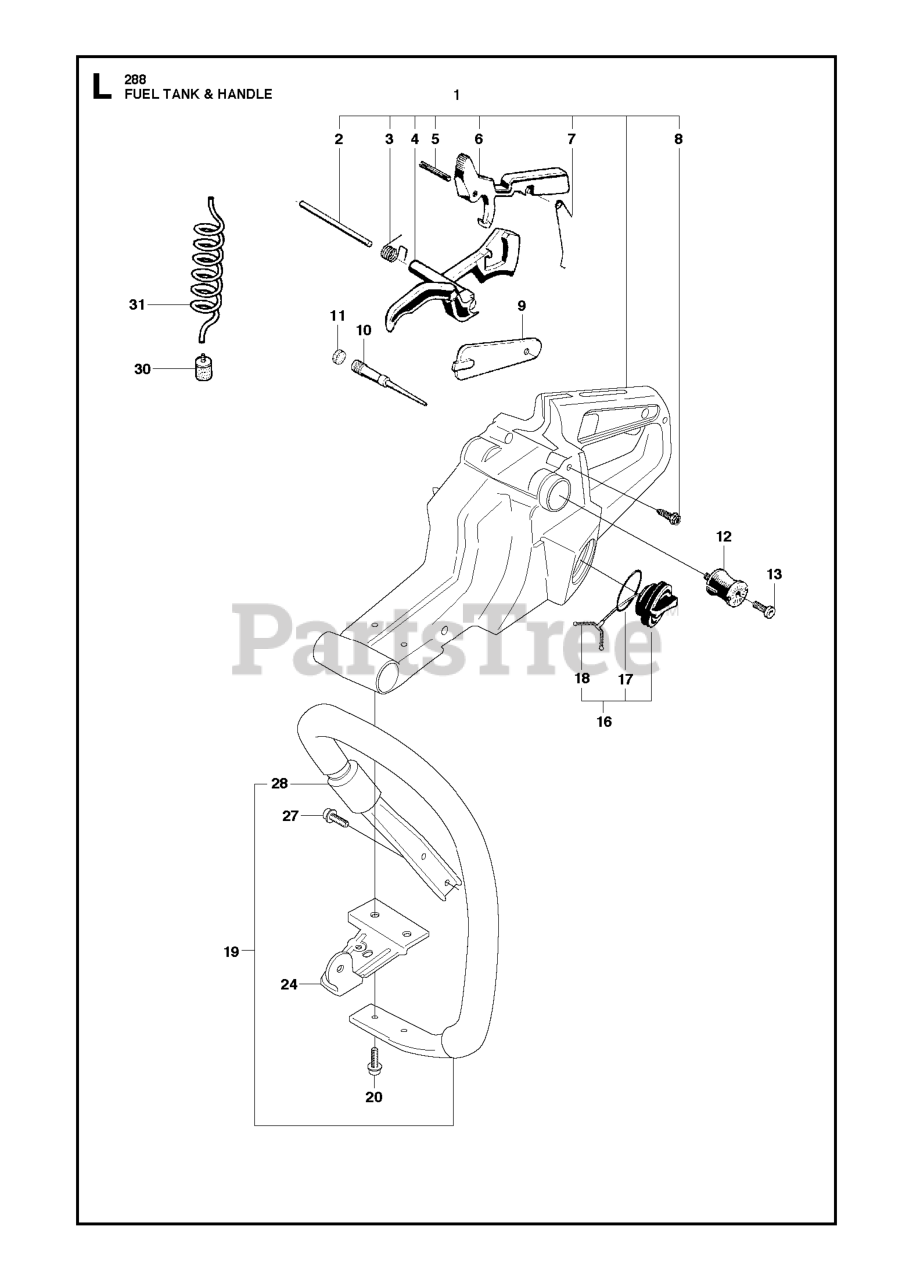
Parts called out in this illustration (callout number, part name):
1	TANK UNIT CPL.
5	SPRING PIN 3X24
6	THROTTLE CATCH
7	SPRING, THROTTLE LOCK
8	SCREW IHSCFT PW5.5X16 8.8 ZN/
9	HANDLE FILLER
10	TANK VALVE
11	FILTER PLUG
12	ANTIVIBE ELEMENT
13	SCREW MC6S 5X12
16	TANK CAP
19	FRONT HANDLE, STD
30	FUEL FILTER
31	FUEL HOSE
